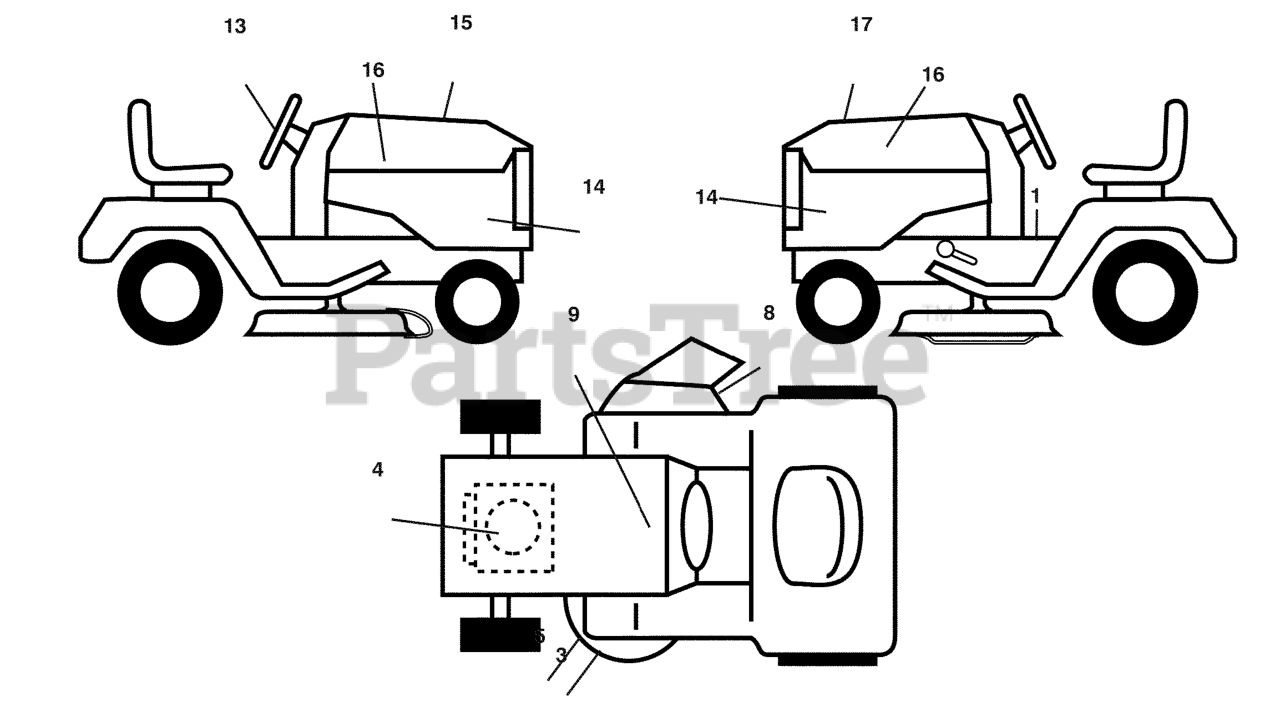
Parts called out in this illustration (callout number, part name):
1	DECAL.FENDER.WARNING.ENG
3	DECAL.WARN.KEEP.HAND.AWAY
4	DECAL, ENGINE, HP
5	DECAL CLUTCH/BRAKE
8	DECAL.MOWER.SCH.48/54
9	DECAL BTRY SYMBOLS
13	DECAL.WHEEL.STRG.LGN.H
14	DECAL PANEL
15	DECAL HOOD CUST. RESP.
16	DECAL.HOOD.NAMELOGO.HUSQ
17	Decal, Replacement
